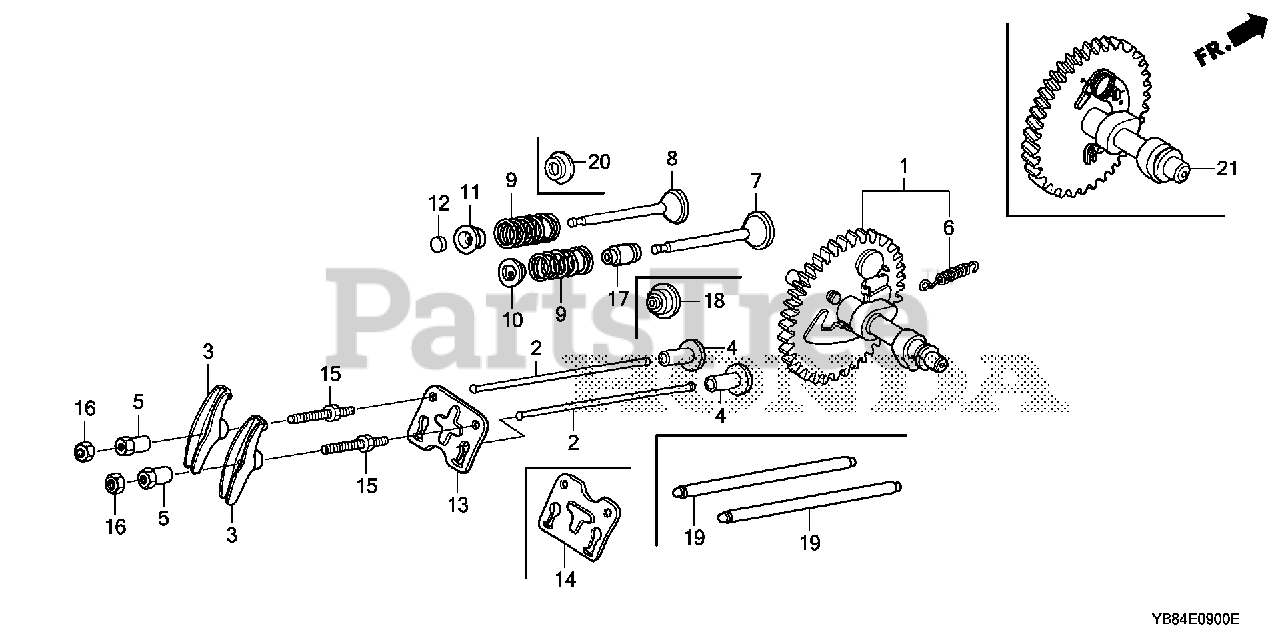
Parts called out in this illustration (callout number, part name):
1	CAMSHAFT ASSY.
3	ARM, VALVE ROCKER
4	LIFTER, VALVE
5	PIVOT, ROCKER ARM
6	SPRING, WEIGHT RETURN
7	VALVE, IN.
8	VALVE, EX.
9	SPRING, VALVE
10	RETAINER, IN. VALVE SPRING
10	RETAINER, VALVE SPRING
11	RETAINER, IN. VALVE SPRING (EXHAUST SIDE)
11	RETAINER, VALVE SPRING
13	PLATE, PUSH ROD GUIDE
15	BOLT, PIVOT (8MM)
16	NUT, PIVOT ADJUSTING
18	SEAL, VALVE STEM
